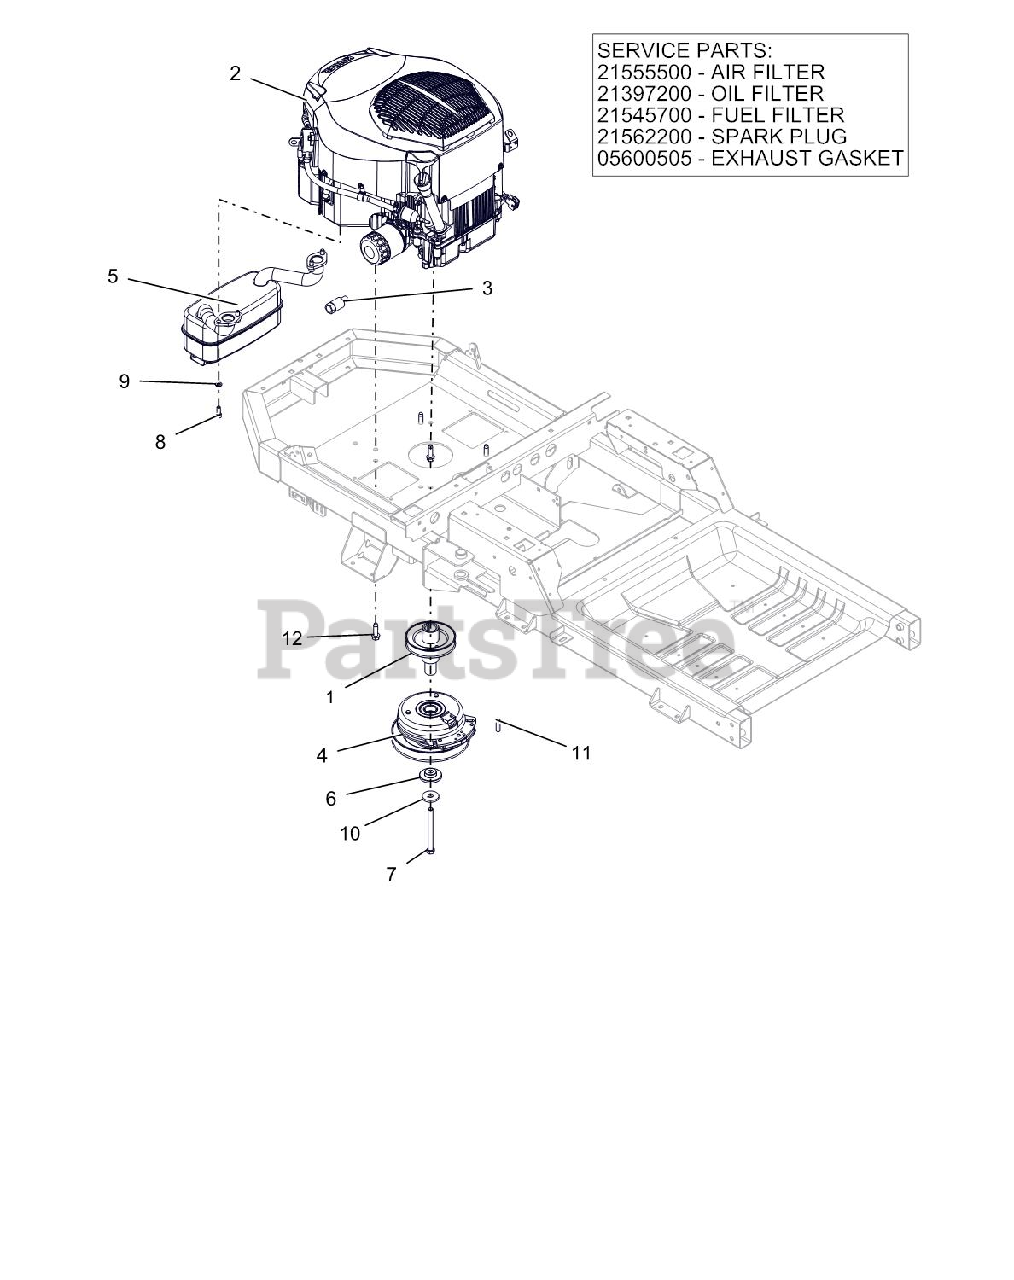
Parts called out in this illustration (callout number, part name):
1	WLDMT, DRIVE SHEAVE-X
2	FILTER, OIL - KOH CV20
2	GASKET, MUFFLER COURAGE TWIN
2	AIR CLEANER, KOHLER
2	ENGINE, KOHLER 24HP TWIN
2	FILTER-FUEL KOHLER COURAGE PRO
2	PLUG, SPARK (RFI)
3	DRAIN, OIL
4	CLUTCH,105FTLB MONOPOLE 6.83"
5	MUFFLER - KOHLER
6	BSHG-FLG .469X1.06X.574X2.0
7	BLT-HEX.438-20X4.5GR8YZ NYTORQ
8	SCR-CAP .31-18X.75 S/HD
9	@WSHR-LK .31X.078 REG YWZC
10	WASHER, 7/16" SPRING DISK
11	KEY-SQ .25 X 1.25 X .25 SAE
12	@SCR-TAP .38-16X1.25 HWH TR YZ
